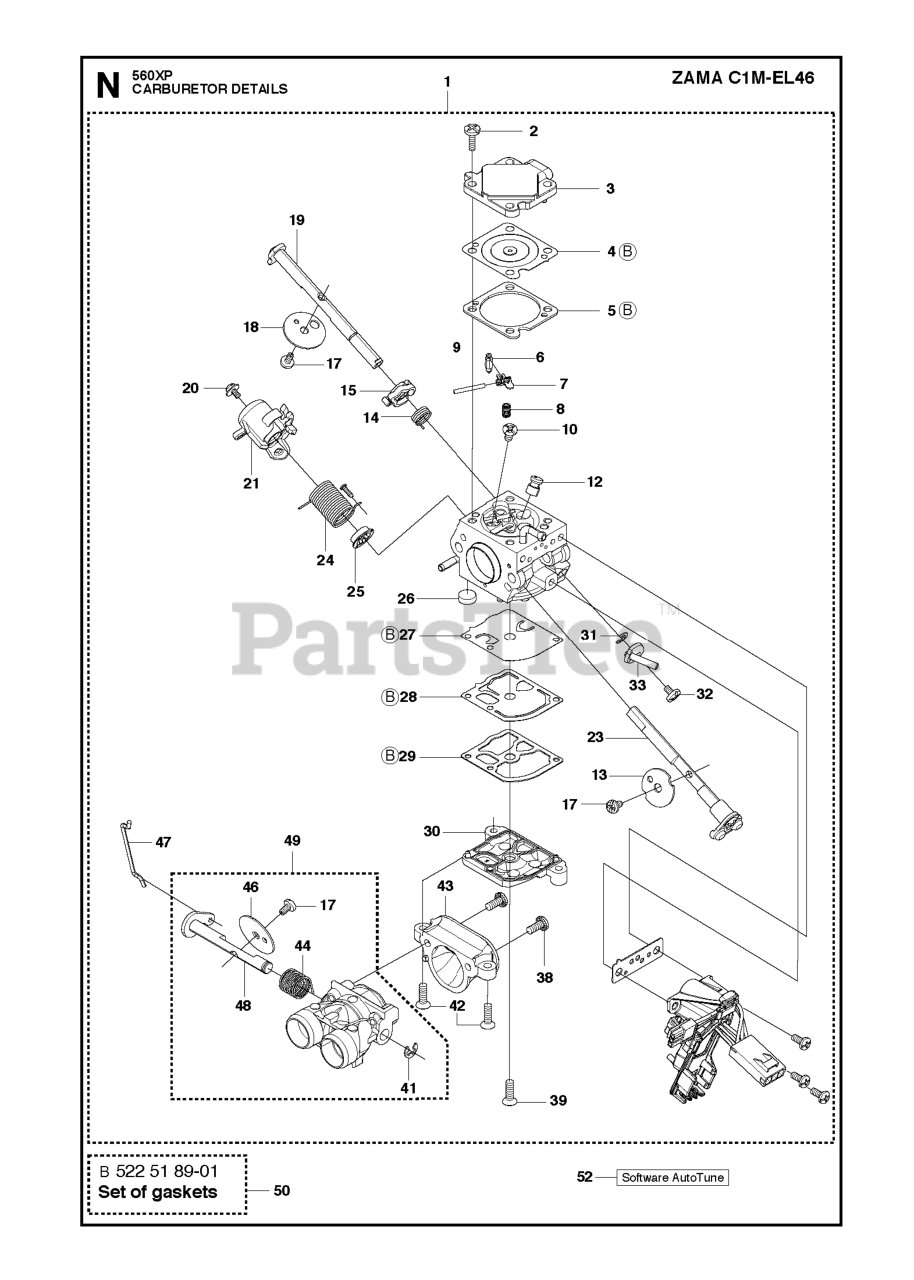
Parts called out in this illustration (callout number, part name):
1	RP CARBURETOR
2	SCREW
3	COVER
4	DIAPHRAGM
5	GASKET
6	INLET NEEDLE
7	LEVER
8	SPRING
9	PIN RETAINING SCREW
10	SCREW
12	MAIN NOZZLE
13	VALVE
14	SPRING
15	LEVER
17	SCREW
18	CHOKE VALVE
19	SHAFT ASSY
20	SCREW
21	THROTTLE LEVER
23	THROTTLE SHAFT
24	SPRING
25	COLLAR
26	STRAINER
27	PUMP DIAPHRAGM
28	DIAPHRAGM
29	GASKET
30	COVER
31	E RING
32	SCREW
33	CHOKE LEVER
38	Screw
39	SCREW
41	CLIP
42	SCREW
43	INLET
44	SPRING
46	THROTTLE FLAP
47	ROD
48	SHAFT ASSY
49	THROTTLE VALVE ASSY
50	KIT GASKET AND DIAPHRAM
52	Husqvarna TBD
